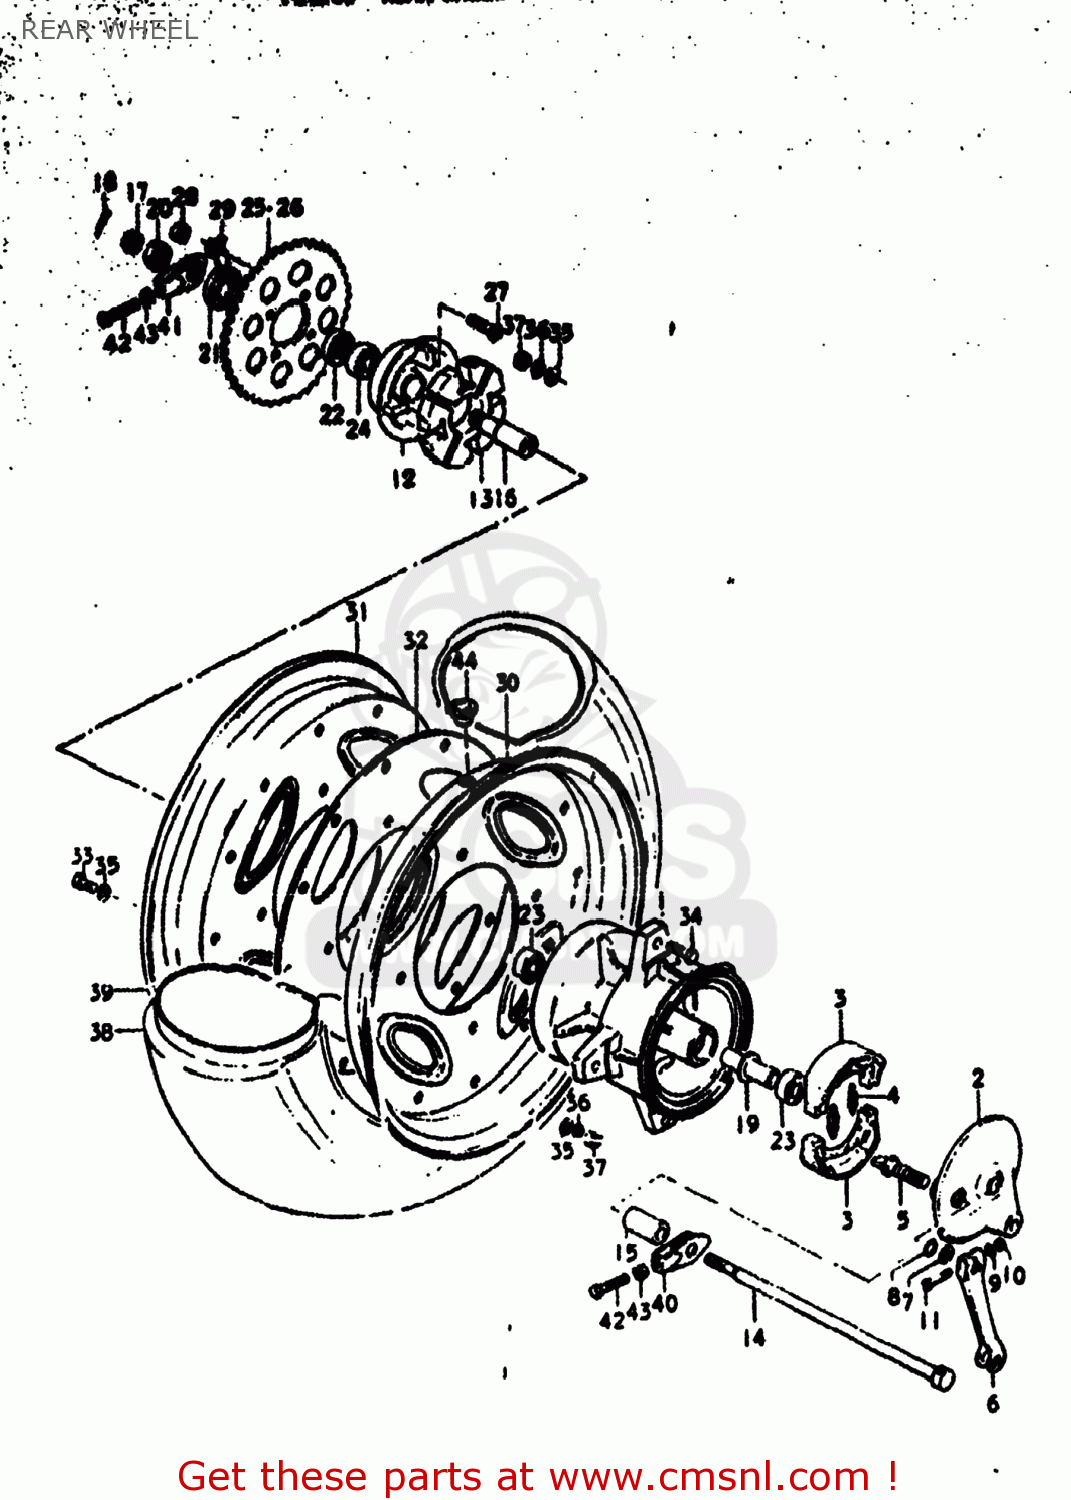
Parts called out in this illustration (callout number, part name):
1	HUB,REAR
2	PANEL,REAR HUB
3	SHOE,BRAKE
4	SPRING(L:34)
5	CAM,FRONT BRAKE
6	LEVER,REAR BRAKE CAM
7	WASHER(12.5X20X1)
8	O RING(D:2.5,ID:11.4)
9	WASHER
10	NUT
11	BOLT
12	DRUM,RR SPROCKET
13	CUSHION,REAR DRUM
14	AXLE,REAR
15	SPACER(15.2X26X33)
16	SHAFT,SPROCKET MOUNTING
17	NUT 12MM
18	COTTER PIN
19	SPACER,REAR HUB BEARING
20	NUT
21	SPACER
22	OIL SEAL
23	BEARING
24	Bearing
25	SPROCKET,REAR 51T
26	SPROCKET,REAR 40T
27	BOLT(8X33.5)
28	NUT
29	WASHER
30	RIM,WHEEL
31	RIM.REAR WHEEL
33	BOLT
34	BOLT 8X28
35	WASHER
36	LOCK WASHER
37	NUT
38	TIRE
39	TUBE,INNER
40	ADJUSTER,CHAIN
41	ADJUSTER,CHAIN
42	BOLT
43	NUT
44	BUSHING
